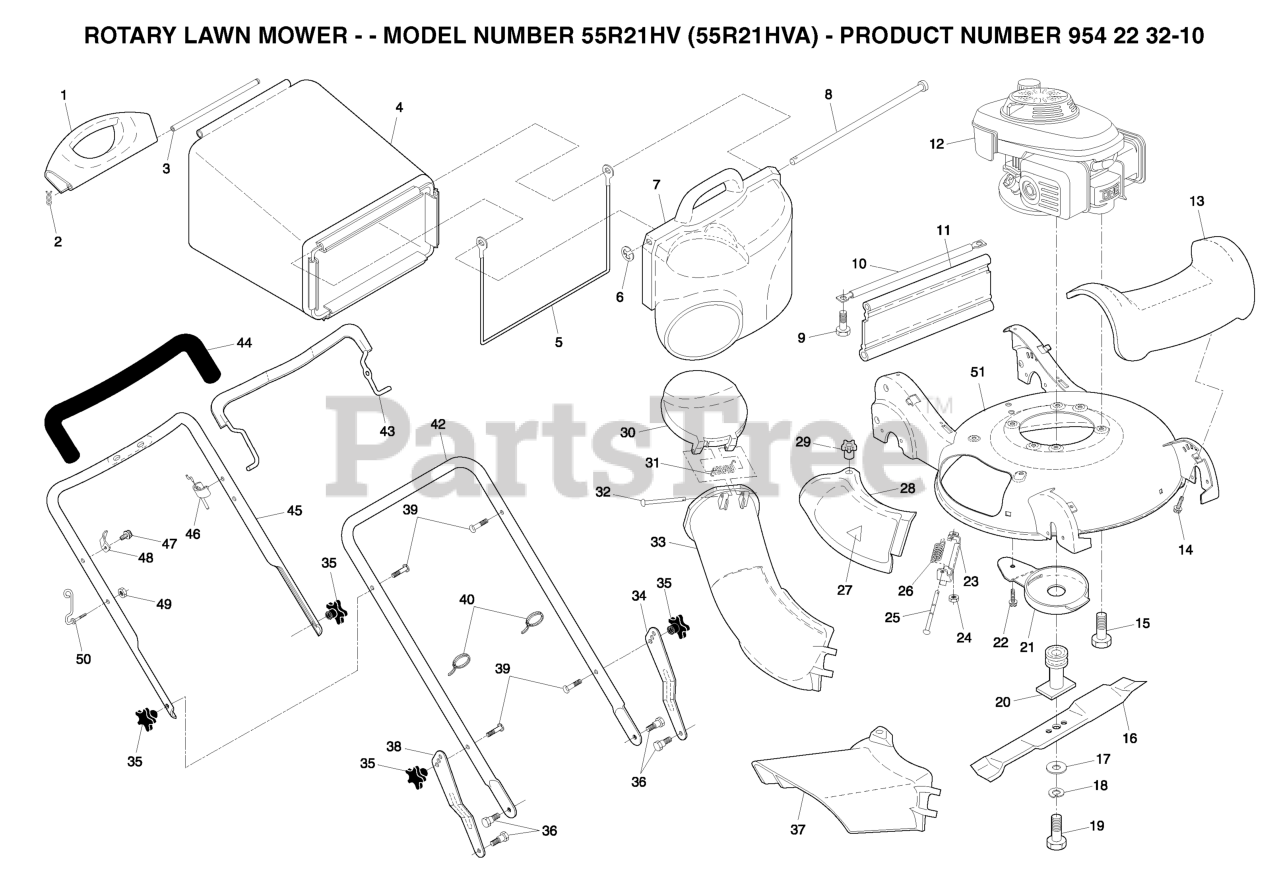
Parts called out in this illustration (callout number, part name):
1	HANDLE, GRASSBAG, REAR
2	COTTER PIN (3 2)(2 2MC)
3	ROD.REAR.HANDLE.YELLOW
4	GRASSBAG
5	GRASSBAG FRAME
7	DOOR, GRASSBAG
8	ROD, PIVOT
9	SCREW.HWH.13-16X1.12
11	SKIRT.REAR.21".HI-VAC.BLACK
13	COVER, FRONT
14	SCREW
15	BOLT 3/8-16X1-1/8
16	21"BLADE (2004 MODEL 55R21HV)
17	WASHER,HARDEN
18	LOCKWASHER
19	SCREW.HX.HEAD.3/8-24
20	BLADE ADAPTOR 7/8 ENG SHAFT
21	DEBRIS SHIELD
22	SCREW 1/4X20
23	BRACKET.ASM.HINGE
24	LOCK NUT
25	ROD.HINGE.1/4"3.82"
26	SPRING.MULCH.DOOR
27	DECAL HYT
28	MULCH DOOR
29	KNOB.MULCH.DOOR
30	DOOR, DICHSRGE CHUTE
32	ROD.HINGE.1/4"3.82"
33	PLASTIC DISCHARGE CHUTE
34	BRACKET
35	KNOB.HANDLE.STAR.HUSQ.GRAY
36	SHOULDER BOLT
37	GUARD.CLIP.ON.21.HV.GRAY
38	BRACKET ADJ LOWER HNDLE RH
39	HANDLE BOLT
40	TIE GUIDE
42	HANDLE.LOWER.GREY
43	BAIL CONTROL
44	GRIP.HANDLE.FOAM.WIDE.(1 SIDE)
45	HANDLE.ASM.UPPER.W/GRIP
46	ASSY ZONE CONTROL
48	BRACKET
50	ROPE GUIDE
51	KIT HOUSING ASSY 21"
